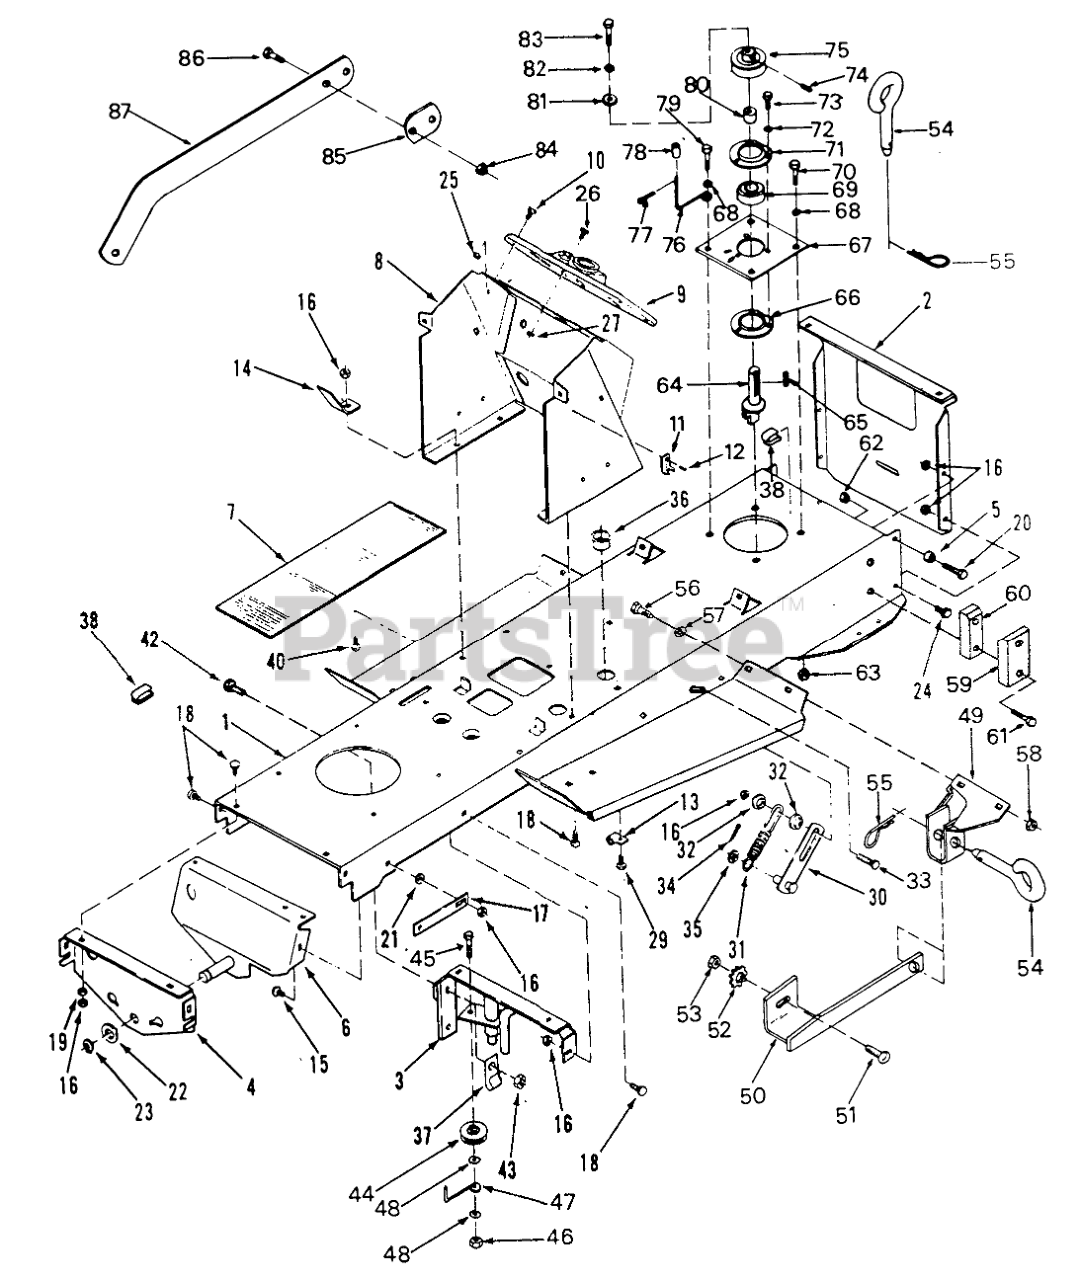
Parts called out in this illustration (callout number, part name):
1	Frame
2	PLATE-DRAWBAR R
3	ASS'Y-FRAME SUPPO R
4	PLATE SUPT - AXLE R
5	Spacer
6	ASS'Y-AXLE SPT RE R
7	PAD-FOOTREST
8	HOODSTAND ASSY B
9	CONSOLE
10	SCREW #10X.62 PHCR
11	Latch Keeper
12	RIVET
13	J-CLIP
14	BRACKET FUSE
15	Bolt-Carriage
16	Nut
17	STRAP R
18	Bolt
19	WASHER 5/16 SAE
20	Bolt
21	Washer-Lock
22	WASHER
23	Snap Ring
24	Bolt
25	Nut
26	Screw
27	Nut
29	Bolt
30	ASSY LINK B
31	SPRING
32	BUSHING
33	Bolt-Carriage
35	WASHER
36	BUSHING-NYLON 1.093
37	CLIP
38	RETAINER
40	Bolt
42	Bolt
43	NUT
44	IDLER PULLEY R
45	Bolt
46	NUT
47	RETAINER BELT R
48	Washer
49	ASS'Y-BRACKET LH R
50	BRACE-WELDMENT L. R
51	Bolt (ONLY used on 212-5SB)
52	WASHER
53	NUT
54	Toolpin (ONLY 1 used on 212-5SB)
55	Hairpin (ONLY 1 used on 212-5SB)
56	Bolt
57	WASHER-SPECIAL
58	Nut
59	Block Rubber
60	SPACER-RUB BLOCK R
61	Screw-Pan Hd.
62	Nut
63	Nut
64	SHAFT-DRIVE
65	KEY
66	BEARING-CUP W/NUTS
67	PLATE-MTG R
68	WASHER 5/16 SAE
69	BEARING-BALL
70	Bolt
71	BEARING-CUP
72	Washer
73	X-REF 321-2
74	X-REF 3246-3
75	PULLEY
76	GUIDE-BELT
77	X-REF 3272-2
78	SPACER
79	Bolt
80	SPACER SHAFT
81	WASHER
82	LOCKWASHER
83	X-REF 323-6
84	NUT
85	SPACER R
86	Bolt
